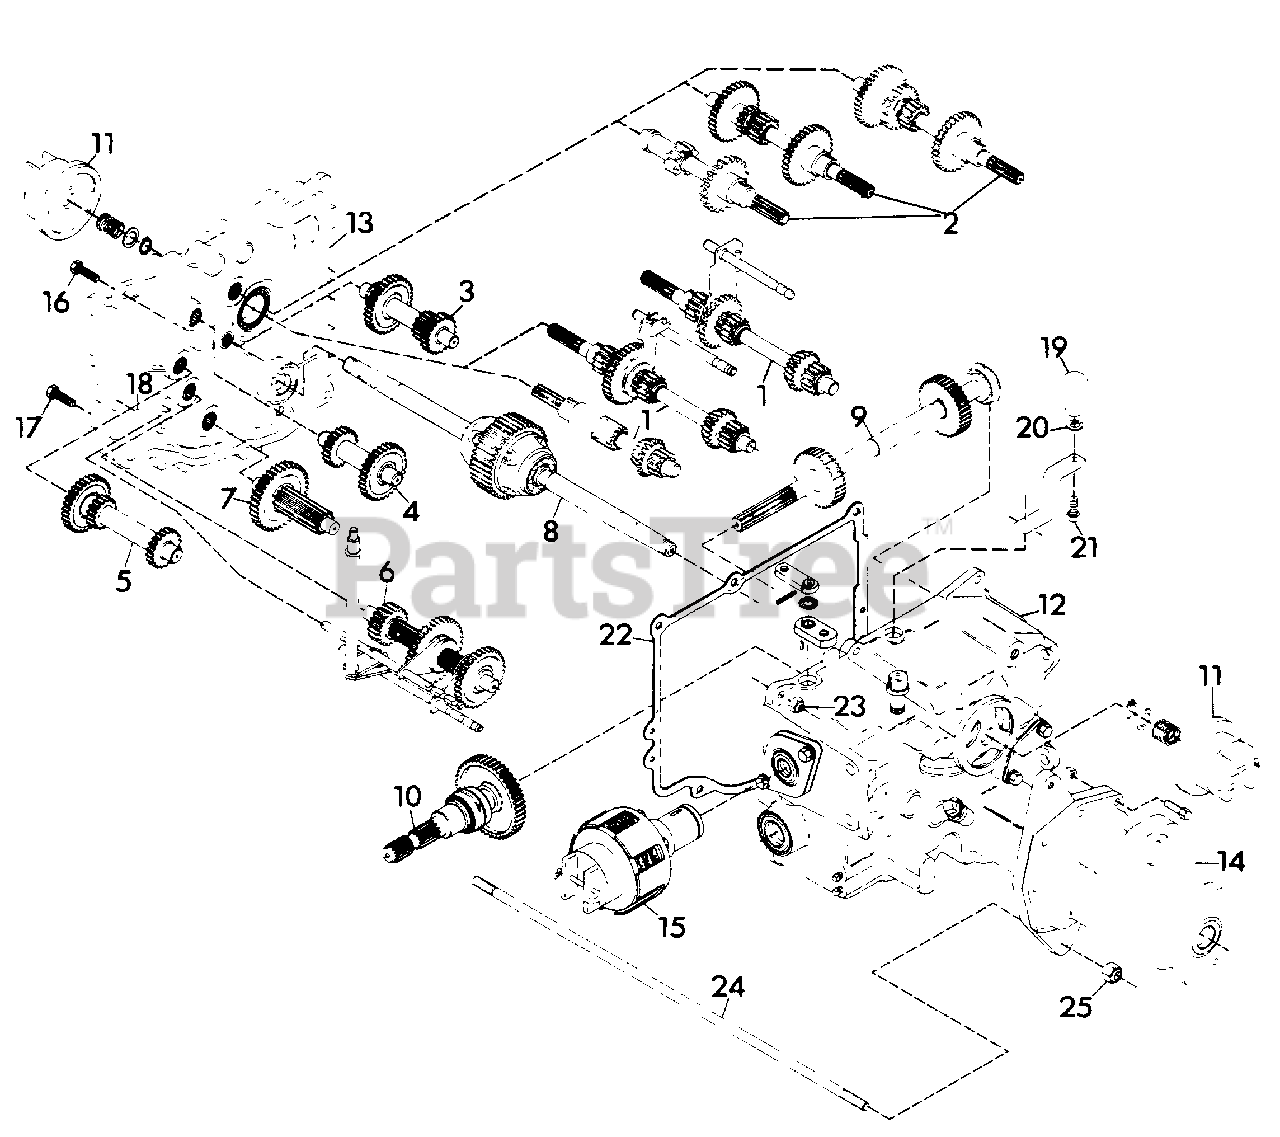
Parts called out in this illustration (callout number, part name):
1	NUMBER 1 SHAFT - FORWARD CLUTCH
2	NUMBER 2 SHAFT - REVERSE CLUTCH
3	NUMBER 3 SHAFT - 3RD AND 4TH GEAR
4	NUMBER 4 SHAFT - IDLER
5	NUMBER 5 SHAFT - 1ST AND 2ND GEAR
6	NUMBER 6 SHAFT - BRAKE/SLIDING GEAR
7	NUMBER 7 SHAFT - PINION/FINAL DRIVE
8	NUMBER 8 SHAFT - DIFFERENTIAL ASM.
9	NUMBER 9 SHAFT - PTO CLUTCH SHAFT
10	NUMBER 10 SHAFT - PTO DRIVE ASSEMBLY
11	NUMBER 11 - FWD-REV CLUTCH ASSEMBLY
12	NUMBER 12 - TRANSMISSION CASE ASM.
13	NUMBER 13 - TRANSMISSION COVER ASM.
14	NUMBER 14 - AXLE HOUSING
15	NUMBER 15 - PTO CLUTCH ASSEMBLY
16	BOLT, HEX 3/8-16X1.50
17	BOLT, HEX 3/8-16X2.25
18	PIN, DOWEL .375X.625
19	KNOB, CONTROL
20	WASHER, LOCK 1/2 REG.
21	BOLT, HEX 1/2-13X.875
22	GASKET, TRANSMISSION COVER
23	NUT, LOCK 3/8-16
24	ROD, STRUT
25	NUT, LOCK 1/2-13
NS	ASSEMBLY, TRANSMISSION, COMPLETE(4-SPD)
NS	ASSEMBLY, TRANSMISSION, COMPLETE(8-SPD)
NS	ASSEMBLY, TRANSMISSION, COMPLETE
